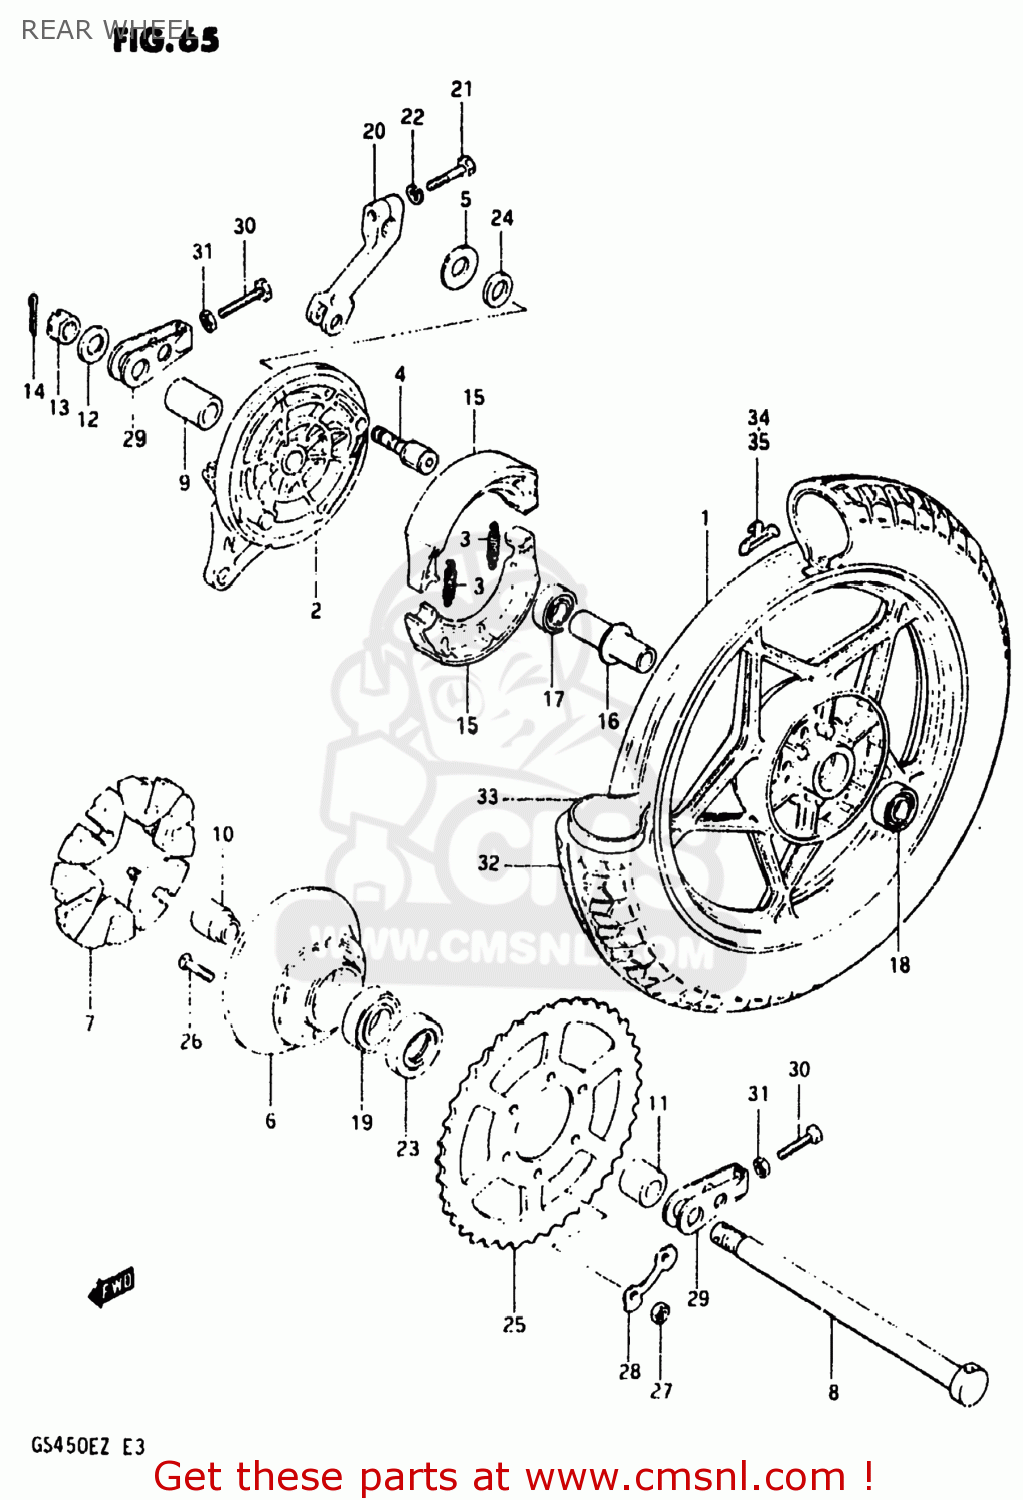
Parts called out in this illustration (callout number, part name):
1	WHEEL,REAR
2	PANEL,REAR HUB
3	SPRING,BRAKE SHOE
4	CAM,FRONT BRAKE
5	WASHER (15X24X1.6)
6	DRUM,REAR SPROCKET MOUNT
7	ABSORBER,RR HUB SHOCK
8	AXLE,REAR
9	SPACER(17.5X28X44.8)
10	SPACER,REAR HUB BEARING
11	SPACER(17X30.5X22.3)
12	WASHER (17X30X3.2)
13	NUT
14	PIN,COTTER
15	SHOE,BRAKE
16	SPACER (17.6X24X57)
17	BEARING
18	BEARING
19	BEARING
20	LEVER,RR BRAKE CAM
21	BOLT
22	LOCK WASHER
23	SEAL,OIL(30.5X52X8)
24	O-RING,BOSS
25	SPROCKET,RR
26	BOLT
27	NUT
28	WASHER
29	ADJUSTER,CHAIN
30	BOLT
31	NUT
32	TIRE
33	TUBE ASSEMBLY,WHEEL,INNER
34	BALANCER,WHEEL
35	BALANCER,WHEEL
